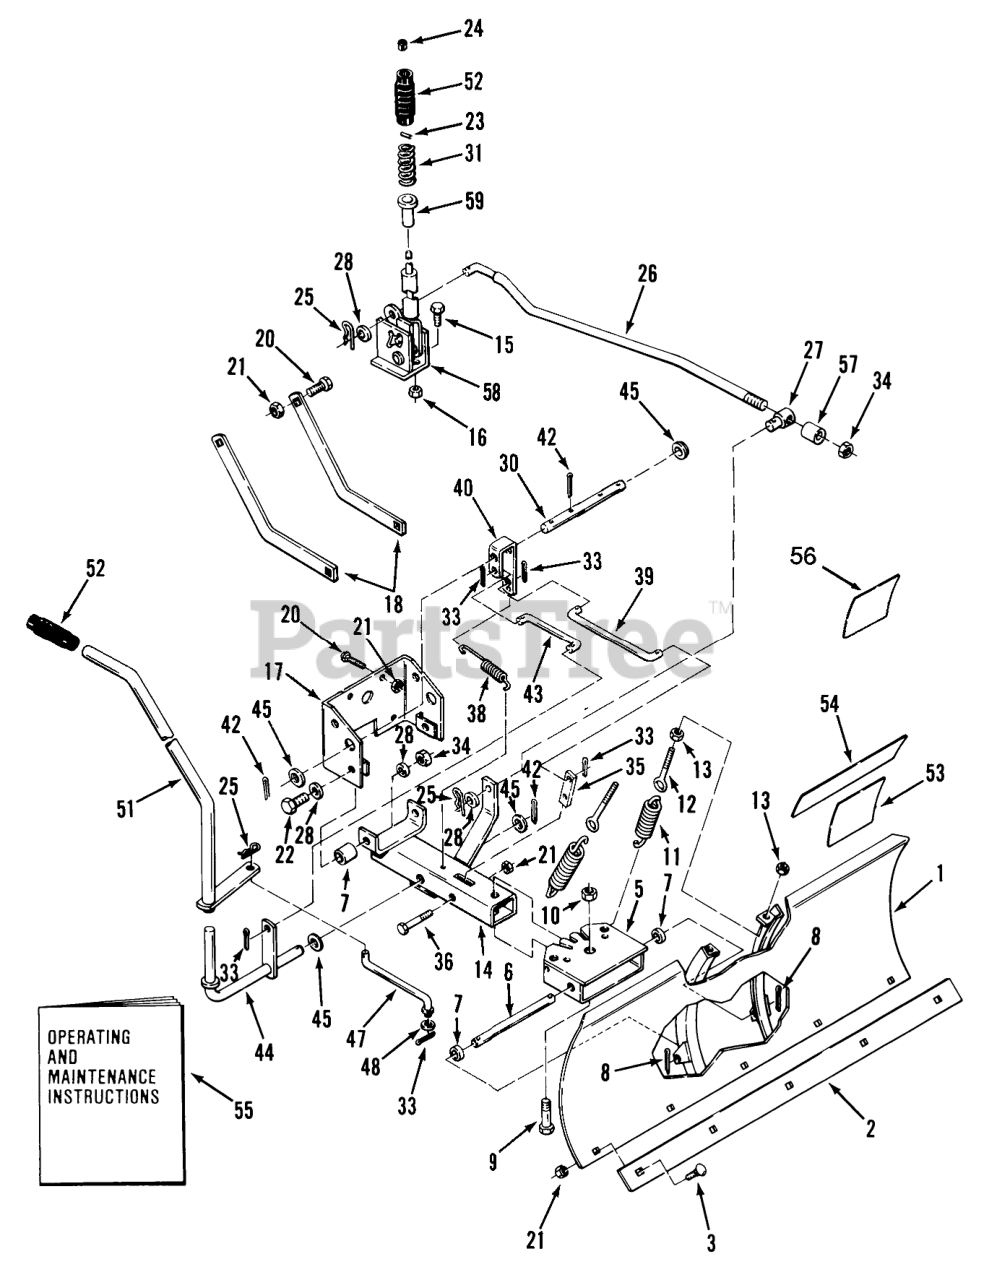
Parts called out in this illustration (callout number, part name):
1	Blade
2	Plate
3	Bolt-Carriage
5	ASS'Y-QUADRANT R
6	ROD-LOWER
7	Spacer
9	HEX HD CAP SCREW
10	Nut
11	SPRING
12	EYEBOLT
13	Nut
14	Frame
15	Bolt-Carriage
16	Nut
17	Front Support
18	BRACE R
20	Bolt
21	NUT
22	Hhcs
23	PIN-SPIROL
24	CAP-ROD, PLUNGER
25	Hairpin
26	ASS'Y-LIFT ROD
27	TRUNION
28	Washer
30	SHAFT R
31	SPRING-COMPRESSION
33	Pop Rivet
34	Nut
35	LATCH-QUADRANT R
36	HHCS
38	SPRING
39	ROD-LATCH
40	BELLCRANK-LATCH R
42	Cotter Pin
43	ROD-BELLCRANK
44	ASS'Y-HANDLE PIVO R
45	Washer
47	ROD-ANGLING
48	Washer
51	ASSY-HANDLE R
52	HANDGRIP
53	DECAL-DANGER
54	DECAL WHEEL HORSE
55	Operating and Maintenance Instructions
56	DECAL-OVERLAY
57	Spacer
58	ASS'Y-LIFT HANDLE R
59	RETAINER-SPRING
